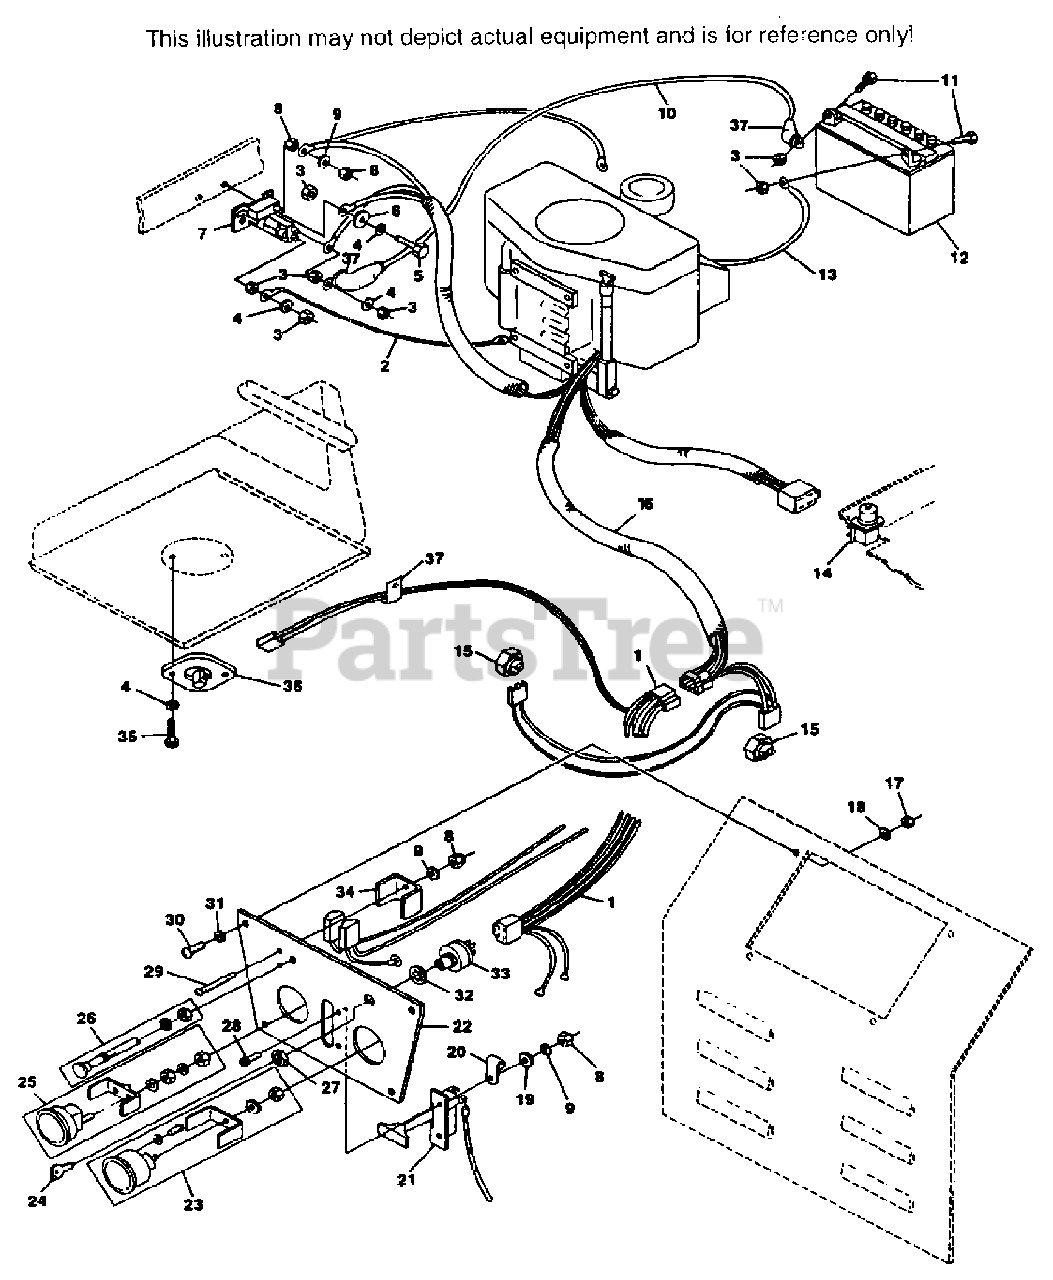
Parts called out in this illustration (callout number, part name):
1	WIRE HARNESS, INSTERMENT PANEL
2	BATTERY CABLE - 9"(RED)
7	SOLENOID
9	LOCKWASHER, # 10 EXTERNAL TOOTH
10	BATTERY CABLE - 30-3/4"(RED)
12	BATTERY
13	BATTERY CABLE - 13-3/4"(BLACK)
14	SWITCH, CUTTER DECK ENGAGE
15	SWITCH, NEUTRAL(N/O)
16	WIRE HARNESS - LOWER
21	THROTTLE CONTROL
22	INSTRUMENT PANEL
23	HOURMETER(INCLUDES HARDWARE)
24	IGNITION KEY
25	AMMETER(INCLUDES HARDWARE)
26	CHOKE CONTROL
27	HEX NUT, 5/8-11
32	LOCKWASHER, 5/8 INTERNAL TOOTH
33	SWITCH, IGNITION
34	BRACKET, FUSE HOLDER
36	SWITCH, SEAT
37	RUBBER BOOT
